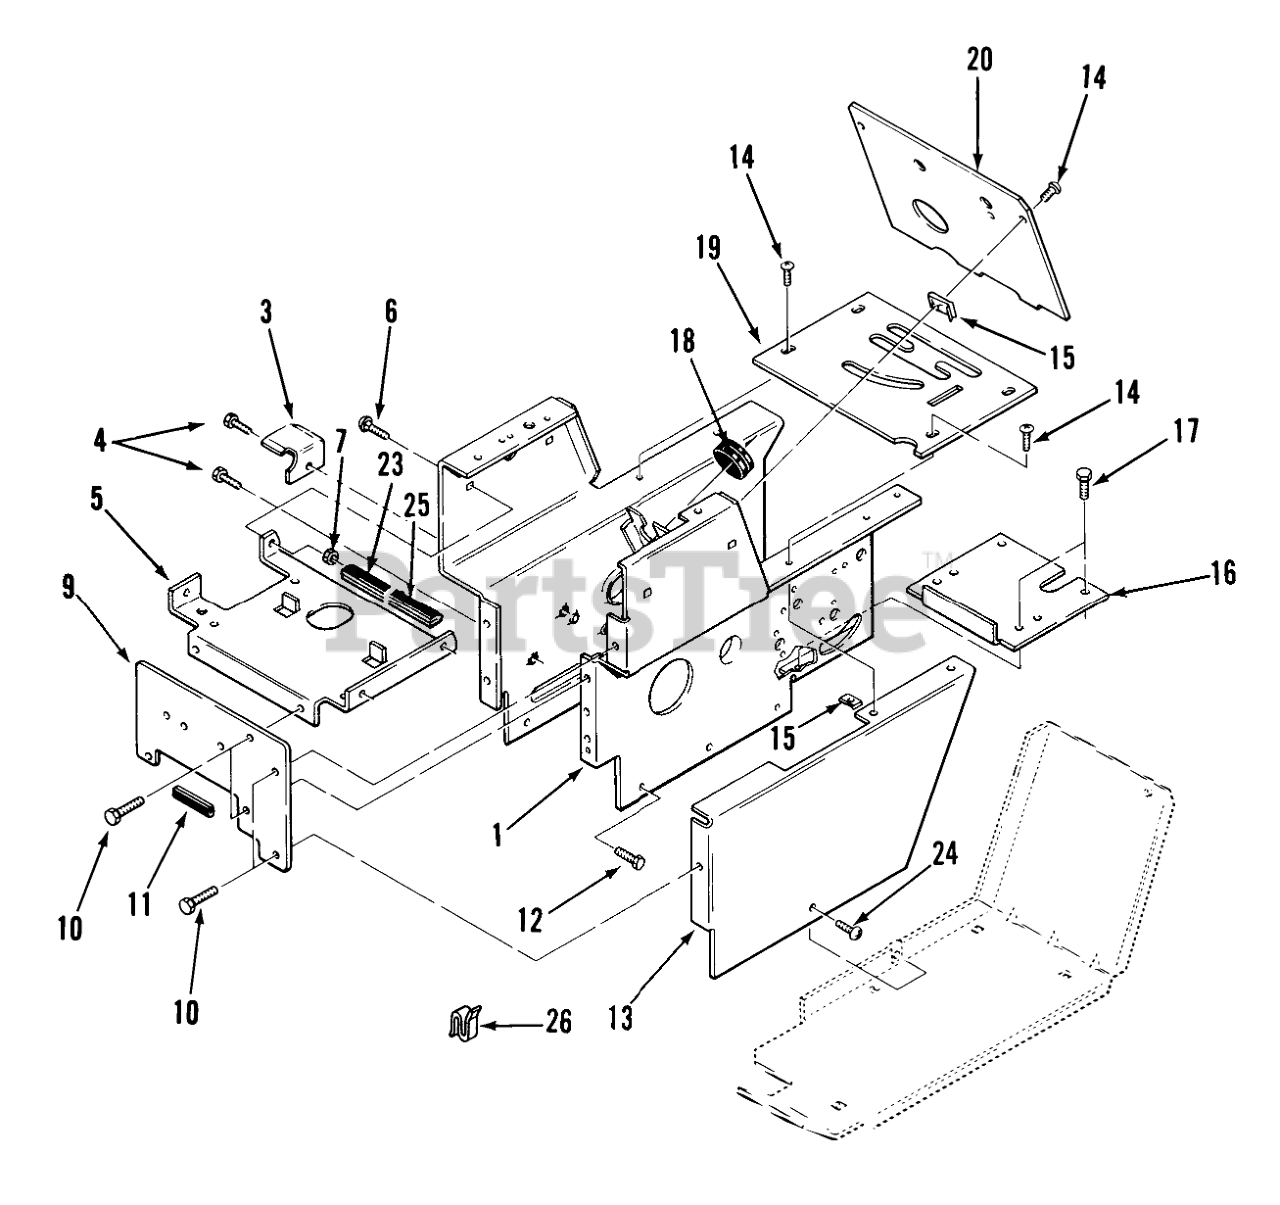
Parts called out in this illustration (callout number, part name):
1	Hoodstand
3	Belt Bracket
4	SCREW
5	SUPPORT-BATTERY B
6	CARRIAGE BOLT -4
7	Nut
9	Front Plate
10	SCREW
11	EDGE TRIM 2" 102896
12	SCREW
12	Bolt
13	Side Cover LH
14	SCREW-PPH
16	Cover-Dust
17	SCREW
18	GROMMET
19	PLATE SHIFT PATTE B
19	Plate-Shift Cover
20	PLATE-HOODSTAND R B
20	PLATE HOODSTAND B
20	Plate-Hood Stand
23	EDGE TRIM 5" OF 102896
24	Screw
25	EDGE TRIM 2" 102896
26	SPEED CLIP
